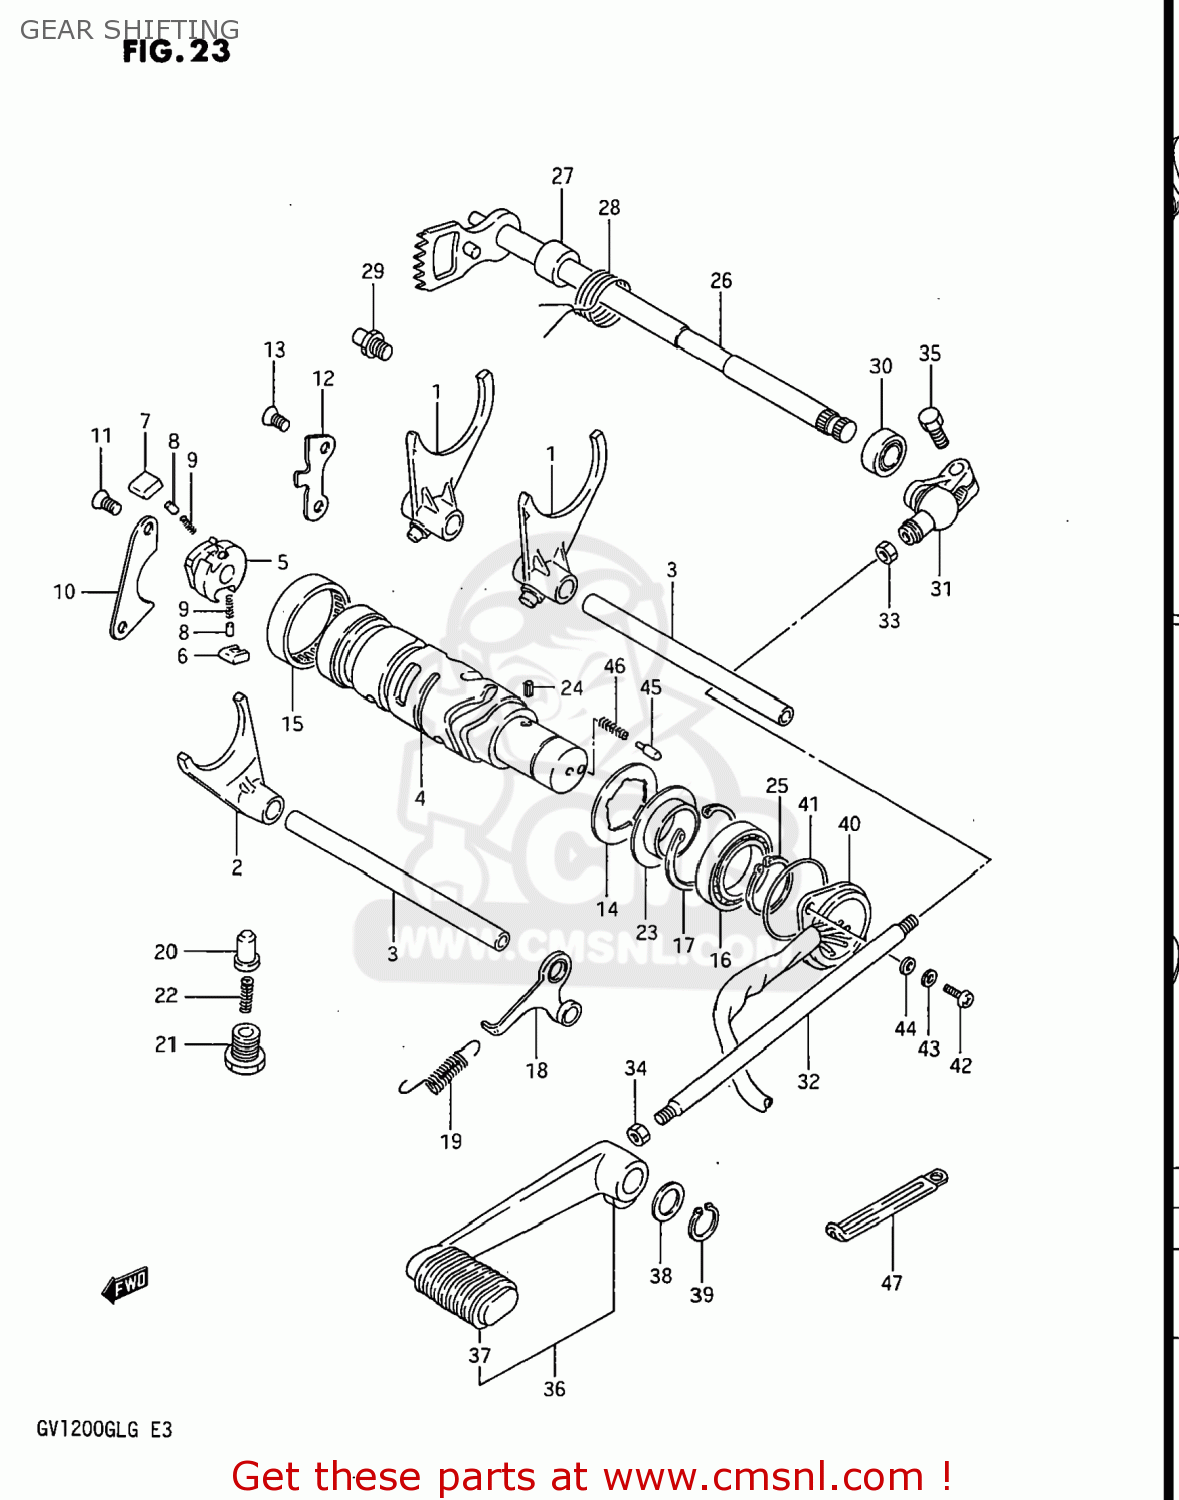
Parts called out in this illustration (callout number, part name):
1	FORK,GEAR SHIFT NO.1
2	FORK,GEAR SHIFT NO.3
3	SHAFT,GEAR SHIFT FORK
4	CAM,GEAR SHIFT
5	GEAR,GEARSHIFT CAM DRIVE
6	PAWL,GEAR SHIFT NO.1
7	PAWL,GEAR SHIFT NO.2
8	PIN(5X8)
9	SPRING
10	LIFTER, PAWL
11	SCREW
12	GUIDE,GEAR SHIFTING CABLE
13	SCREW
14	WASHER,LOCK
15	BEARING(43X49X12)
16	BALL BEARING
17	CIRCLIP,42MM
18	STOPPER,GEAR SHIFTING
19	SPRING
20	STOPPER,GEAR SHIFTING
21	HOLDER,GEAR SHIFT CAM STOP SPR
22	SPRING
23	PLATE,STOPPER
24	PIN 4X6
25	CIRCLIP,25MM
26	SHAFT,GEAR SHIFT
27	SPACER(12X20X15.3)
28	SPRING
29	STOPPER,GEAR SHIFT CAM
30	OIL SEAL
31	ARM,GEAR SHIFT SHAFT
32	ROD,GEAR SHIFT LINK
33	NUT
34	NUT 6MM
35	BOLT
36	LEVER ASSEMBLY,GEAR SHIFTING
37	RUBBER,GEAR SHIFT PEDAL
38	WASHER(12.5X20X1)
39	CIRCLIP
40	TERMINAL BASE,NEUTRAL
41	O RING(D:2.4,ID:36.5)
42	SCREW(5X14)
43	LOCK WASHER
44	WASHER
45	PIN(5X15.5)
46	SPRING
47	CLAMP
